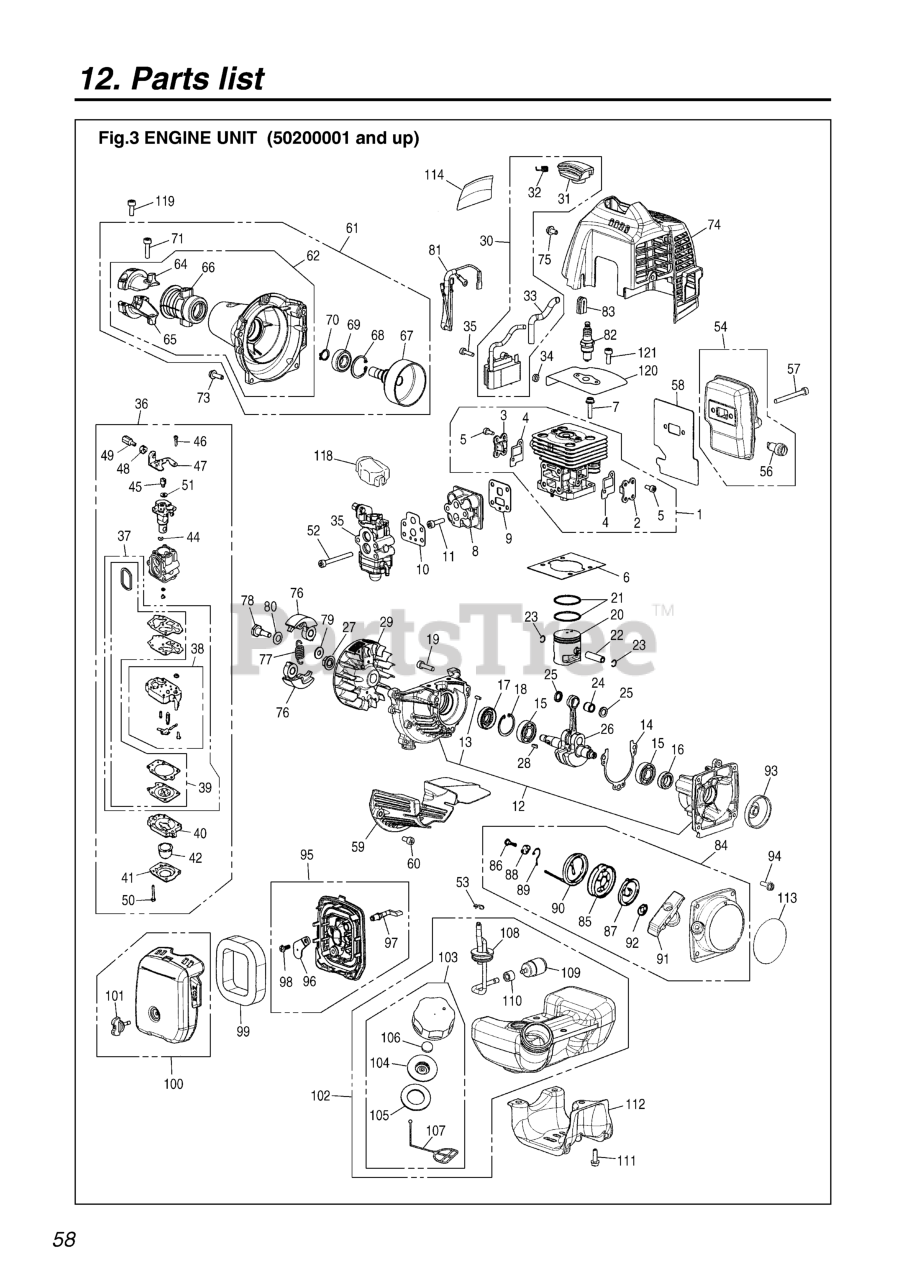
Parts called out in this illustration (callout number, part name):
1	CYLINDER-C
2	SHAFT (RPLS -12212)
3	GRIP (RPLS 3577-32140 & 3220-
4	LEVER ASSY. (RPLS. T3002-12203
5	LEVER ASSY (RPLS. 6110-14412)
7	COVER (USE 848-8RA-0340)
8	FLEX, TRIGGER
16	CORD (A), BLACK
17	CORD (B), RED
18	TUBE (RPLS 4900-72141)
19	CABLE (RPLS 5580-83100)
20	HANGER COMP.
23	SCREW
24	NAME PLATE
25	GRIP
26	SPRING
27	STRAP ASSY.
28	TOOL-SET
29	SCREWDRIVER
31	WRENCH (TOOL)
32	SPANNER, 8 X 10 (RPLS 2540- )
33	GOGGLE
77	SPRING
78	BOLT
79	WASHER, FLAT (USE 182303)
80	WASHER (RPLS -51241)
81	CORD COMP.
83	GROMMET
84	RECOIL-A
85	REEL
86	SCREW
87	SPRING, SPIRAL
88	COLLAR
89	ARM
90	ROPE (REPLACES 4500-75160)
91	KNOB (RPLS -75420)
92	PLATE, STOPPER
93	PULLEY
94	BOLT, TORX
95	BODY ASSY (RPLS T1551-82100)
96	PLATE, CHOKE
97	LEVER
98	SCREW
99	ELEMENT
100	COVER-A (RPLS T1551-82200)
101	KNOB
102	TANK-A
103	CAP ASSY (RPLS -85201)
104	HOLDER (REPLACES -85230)
105	PACKING
106	FILTER
107	STOPPER
109	FILTER ASSY
111	BOLT
112	GUARD, TANK
113	LABEL, RECOIL
114	LABEL, COVER
118	COVER
119	BOLT
120	PLATE
121	BOLT
A2	BEARING
A3	GEARCASE COMP (RIGHT)
A5	BOLT, M5 x 12
A6	FITTING, GREASE
A7	SCREW
A8	NUT
A9	BOLT, M6 x 30
A10	SHIM
A12	COVER, CHAIN
A13	NUT
A14	GEAR, WORM
A15	PUMP ASSY, OIL
A16	SCREW, M4 x 10
A17	GASKET
A18	PIPE ASSY, OIL
A19	PIPE, OIL
A20	FILTER
A21	TANK ASSY, OIL
A22	COLLAR
A23	VALVE
A24	SCREW, M5 X 12
A25	CAP ASSY, OIL
A26	GASKET, OIL CAP
A27	SHAFT, GEAR
A28	GEAR, BEVEL
A29	BEARING (RPLS T3403-13530)
A31	RING, SNAP (RPLS T3300-13330)
A32	RING, SNAP, M24 x 1.2
A33	COLLAR
A34	SPROCKET
A35	LABEL (PSZ2500)
A36	WASHER
A37	SCREW
A38	12
A39	12
